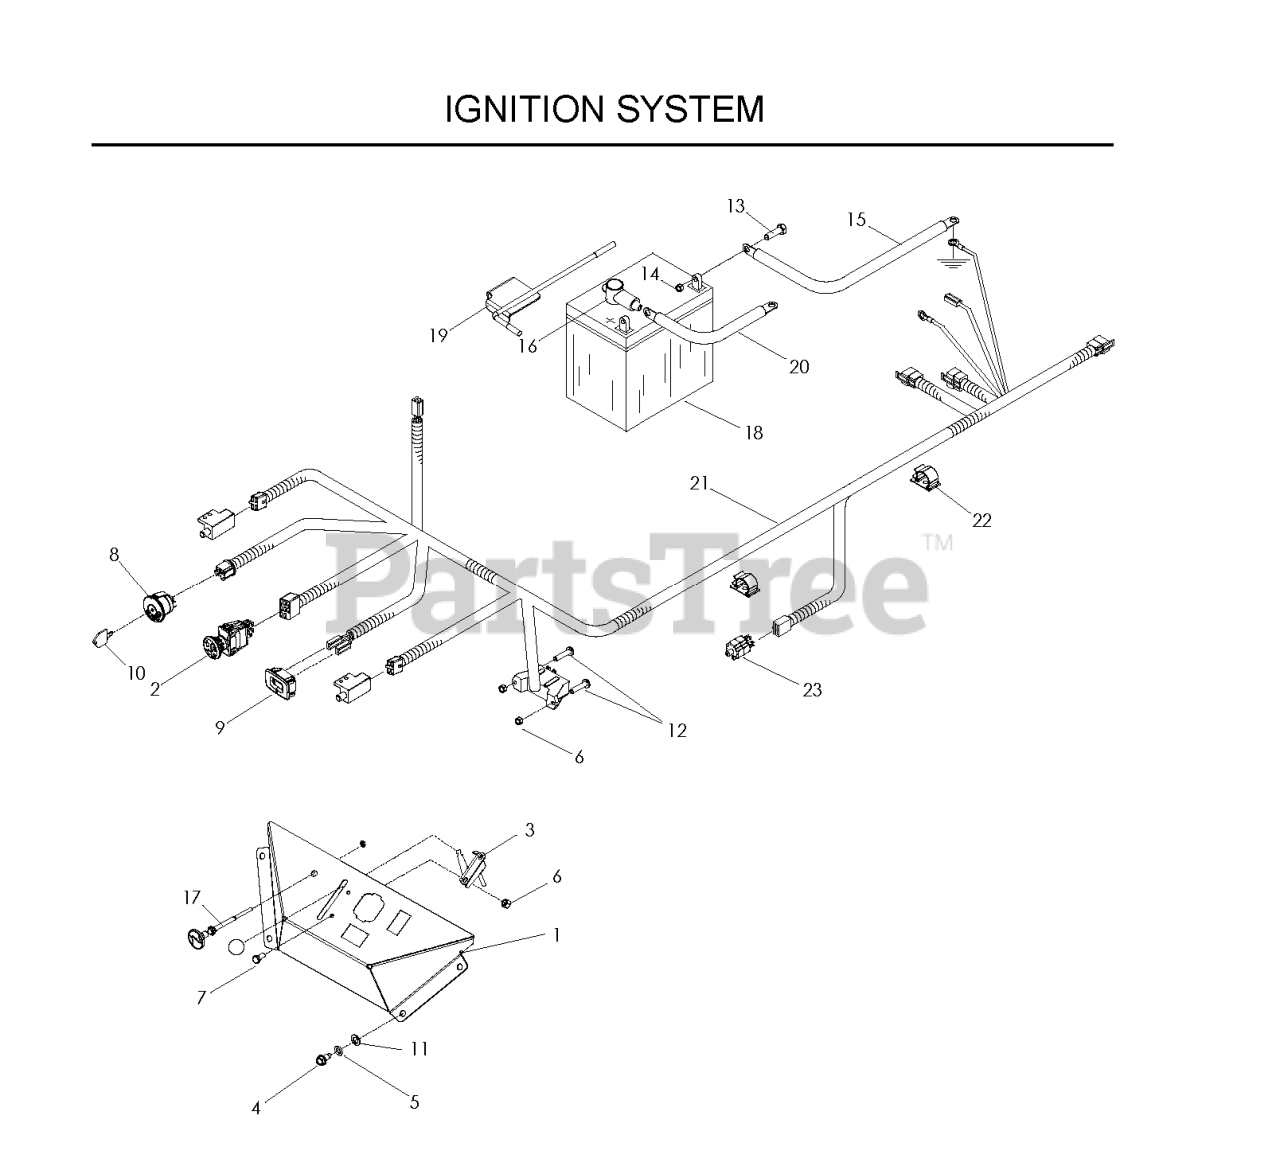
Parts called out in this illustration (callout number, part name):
1	CONSLE, ORANGE
2	SWITCH, PTO 10 AMP
3	THROTTLE CABLE
4	SCREW 1/4 X 5/8
5	LOCKWASHER 1/4"
6	NUT 10-24 NYLOC
7	HCS #10-24 X 1/2
8	RP IGNITION SWITCH
9	HOUR METER
10	KEY
11	WASHER 1/4 FLAT
12	SCREW, #1--24 X 1/2 SLOTTED
13	HCS 5/16C X 3/4
14	NUT 5/16 NYLOC
15	CABLE-NEGATIVE
17	CONTROL-CHOKE 51"
18	BATTERY, 12 V 330 AMP
19	BATTERY HOLD DOWN
20	CABLE POSITIVE, LONG
21	HARNESS, WIRING LZ/IZ
22	PUSH-MOUNT WIRE CLIP
23	SWITCH, BRAKE 3P
